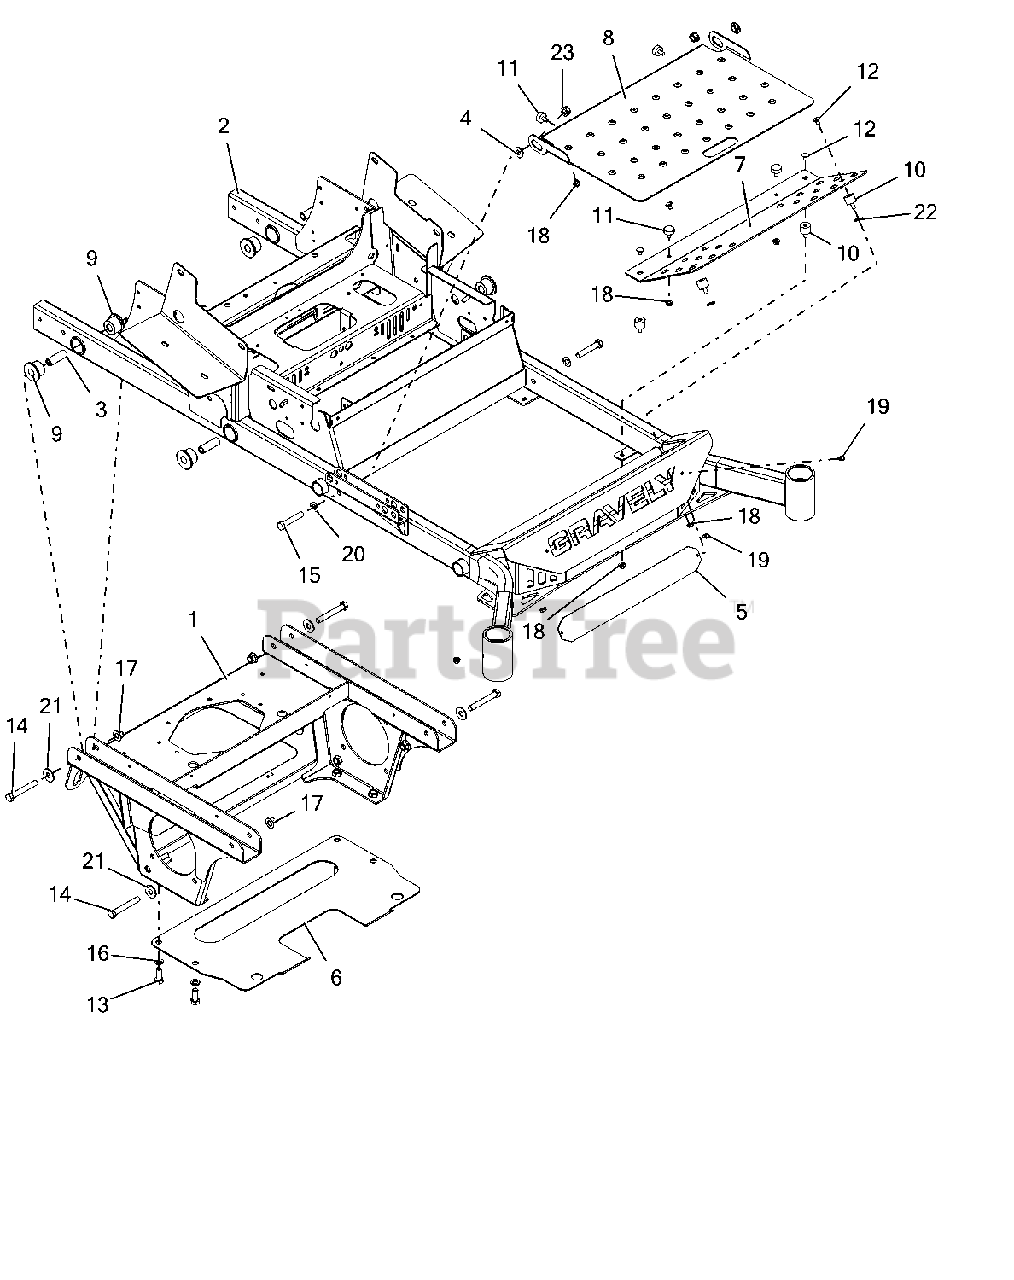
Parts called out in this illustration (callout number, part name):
1	PT200/400 AXLE/ENG FRM WMT-RED
2	52-60"PT200/400 FRAME W/DECALS
3	BSHG-SLV .50X.75X2.23
4	BSHG-FLG .515X.750X.395X1.120
5	BUMPER LOGO BACKING PLATE -BLK
6	PLATE-TRANSMISSION SKID
7	FOOTREST W/ SAFTEY DECALS
8	INSPECTION PANEL W/SAFE DECAL
9	BSHG-FLG .75X1.51X1.13X2.0 URE
10	BUMPER,STUD MNTD W/FEMALE INSR
11	BUMPER, RUBBER
12	BLT-RDHDSQNK .31-18X.50 G5YZ
13	@BLT-HEX .50-13X1.25 GR5 YWZC
14	@BLT-HEX .50-13X3.50 GR5 YWZC
15	@BLT-HEX .50-13X2.75 GR5 YWZC
16	@WSHR-LK .50X.125 REG YWZC
17	@NUT-LK-NYL-FLG .50-13 YWZC
18	NUT-SPNLK-FLG .312-18 YWZC
19	SCR-TAP .25-20X.50 HWH TR YWZ
20	WSHR-FL-STL.531X1.00X.063 YWZC
21	@WSHR-FL-STL.563X1.38X.109YWZC
22	WSHR-FL-STL.38X.875X.083 YWZC
23	NUT-LK-CTR-FLG .50-13 YWZC
